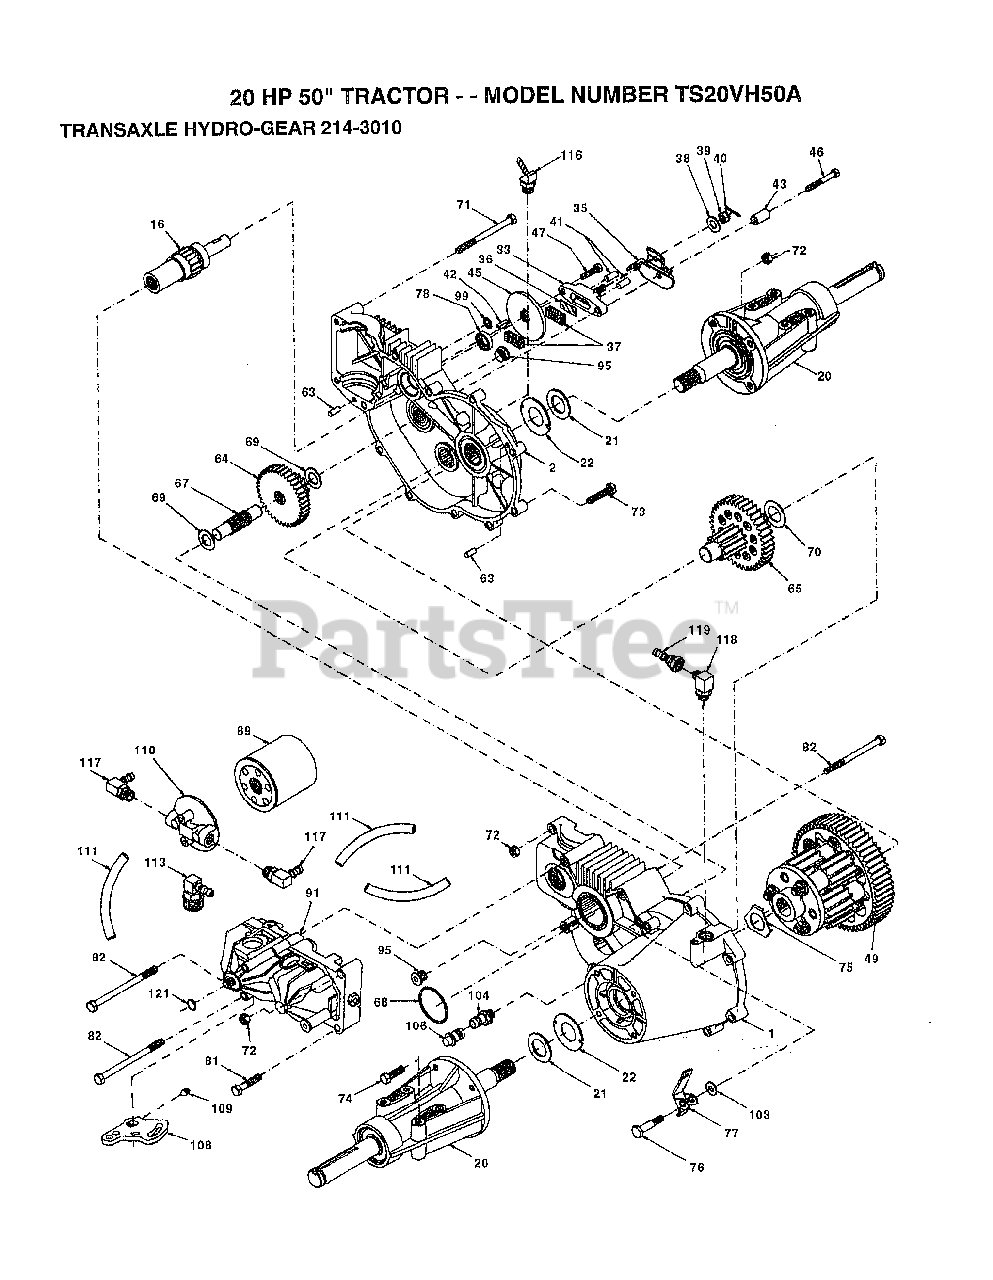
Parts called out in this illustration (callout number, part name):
1	HOUSING LH 70086
2	HOUSING RH 70088
16	SHAFT BRAKE 62877
20	AXLE MTG 70087
21	WASHER 44805
22	WASHER 44806
33	YOKE.BRAKE.62589
35	ARM BRAKE 50214
36	PUCK PLATE 44134
37	PUCK BRAKE 44132
38	WASHER HYD 44130
41	PIN BRAKE 44127
42	KEY HI PRO 44143
43	SPACER 50259
45	DISC BRAKE 44090
46	BOLT 1/4-20 44276
47	BOLT 1/4-20 44433
49	DIFFERENTIAL62834
63	PIN DOWL 44757
64	GEAR R14-38 44775
65	PINION DRIV 70051
67	SHAFT-44779
68	O RING 44781
69	WASHER 44795
70	WASHER 44794
71	BOLT 5/16 44827
72	NUT HXLK 43064
73	BOLT 5/16 44841
74	SCREW 5/16 45089
75	WASHER DIF 44880
76	BOLT SHOULD 44785
77	ARM FREEWHL 44786
78	SEAL.OIL.44761
81	BOLT 5/16 43084
82	BOLT 5/16 44820
89	FILTER SPIN 50037
95	PLUG.9005110-5600
103	WASHER.50169
104	CAP.VENT.70109
106	O-RING.ASM.70110
108	ARM.CONTROL.45007
109	SCREW.SET.50018.
110	FILTER.HEAD.50207
111	HOSE.5/16.50208.
113	FITTING.SAE.50210
116	FITTING.SAE.50213
117	FITTING.SAE.50249
118	FITTING.MAL.50251
119	FITTING.FEM.50250
121	RING.RET.2003016.
